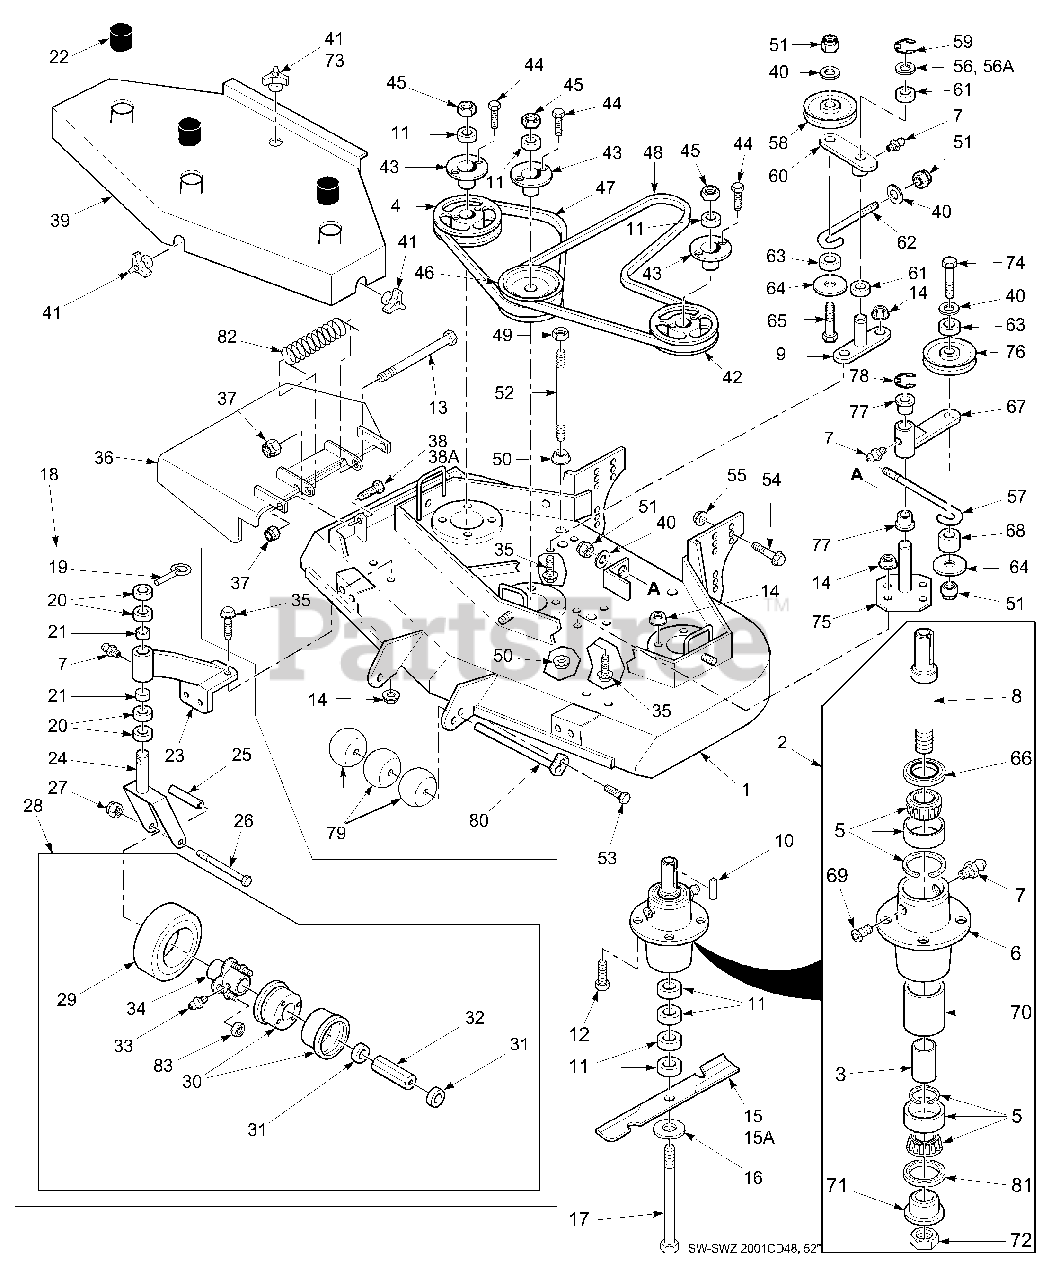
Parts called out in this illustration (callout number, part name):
1	Cutter Deck
2	Spindle Assembly
3	Spacer, Inside
4	Pulley
5	Tapered Bearing (Two)
6	Spindle Housing
7	Grease Fitting Str. 5/16"
8	Spindle Shaft, Tapered Brng
9	Idler Pivot
10	Key, 1/4 x 1/4 x 2"
11	Spacer, Cutter Blade - Small
12	Bolt, 5/16-18 x 1-1/4" Hex Head
13	Bolt, 5/16-18 x 4-3/4" Hex Head
14	Serrated Flange Nut, 5/16-18
15	Cutter Blade 16-1/2" Marbain
15A	Cutter Blade 16-1/2 High Lift Marbain
15A	Cutter Blade 18 High Lift Marbain
16	Flatwasher,5/8" (.688 x 1.75 x .134)
17	Hex Head Bolt, 5/8-11 x 9-1/2"
18	Caster Assembly
19	Quick Pin
20	Spacer, Caster Yoke, 1/2" thick
21	Bronze Bearing
22	Spindle Shield
23	Support Assembly
24	Caster Yoke
25	Sleeve, Caster Wheel Bearing
26	Hex Hd Bolt, 1/2-13 x 5-1/2"
27	Elastic Stop Nut, 1/2-13
28	Wheel Assy.
29	Tire only, Caster Wheel
30	Rim Pair, Caster Wheel
31	Bearing Retainer, Caster Wheel
32	Roller Bearing, Caster Wheel
33	Grease Fitting 45 deg., 1/4-28
34	Hub Assembly
35	Capscrew, 5/16-18 x 3/4"
36	Discharge Chute
37	Nut, 5/16-18 Elastic Elastic Stop
38	Bolt, 5/16-18 x 1-1/2" Hex Head (Front)
38A	Bolt, 5/16-18 x 1-3/4" Hex Head (Rear)
39	Belt Cover
40	Flat Washer, 3/8" Special
41	Wing Nut, 3/8-16 (Large)
42	Pulley
43	Tapered Hub
44	Bolt, 1/4-20 x 3/4" Hex Head
45	Nut, 5/8-11 Hex
46	Pulley, Double
47	Belt, RH Blade Drive
48	Belt, Blade Drive
49	Nut, 3/8-16, Nut Centerlock
50	Nut, 3/8-16, Serrated Flange
51	Nut, 3/8-16 Elastic Stop
52	Support, Belt Cover
53	Bolt, 5/16-18 x 1/2" Hex Head
54	Cpscrw,7/16-14 x 1" Ser Flng Hex Hd
55	Nut, 7/16-14 Serrated Flange
56	Flat Washer 3/4" Special
56A	Flat Washer 3/4" Special
57	J-Hook
58	Idler Pulley, "V" Groove
59	Retaining Ring, 3/4" Ext."E"
60	Idler Arm Assy.
61	Bronze Bearing
62	J-Rod, Idler Pulley
63	Spacer, J-Rod
64	Washer, 3/8 x 1-1/2 x 16 ga.
65	Bolt, 3/8-16 x 2-1/4" Hex Head
66	Seal, Cutter Spindle
67	Idler Arm Assy
68	Spacer, J-Rod
69	Reiief Fitting, Cutter Spindle
70	Spacer, Outside, Cutter Spindle
71	Spindle Bushing
72	Nut, Cutter Spindle
73	Wing Nut, 3/8-16 (Small) Top Side
74	Bolt, 3/8-16 x 3-1/2" Hex Head
75	Idler Pivot
76	Idler Pulley, Belt Clutch
77	Bronze Bearing
78	Retaining Ring
79	Guide Roller
80	Roller Shaft
81	Seal, Cutter Spindle
82	Spring, Chute Return
83	Nut, 3/8-24 Tapered
